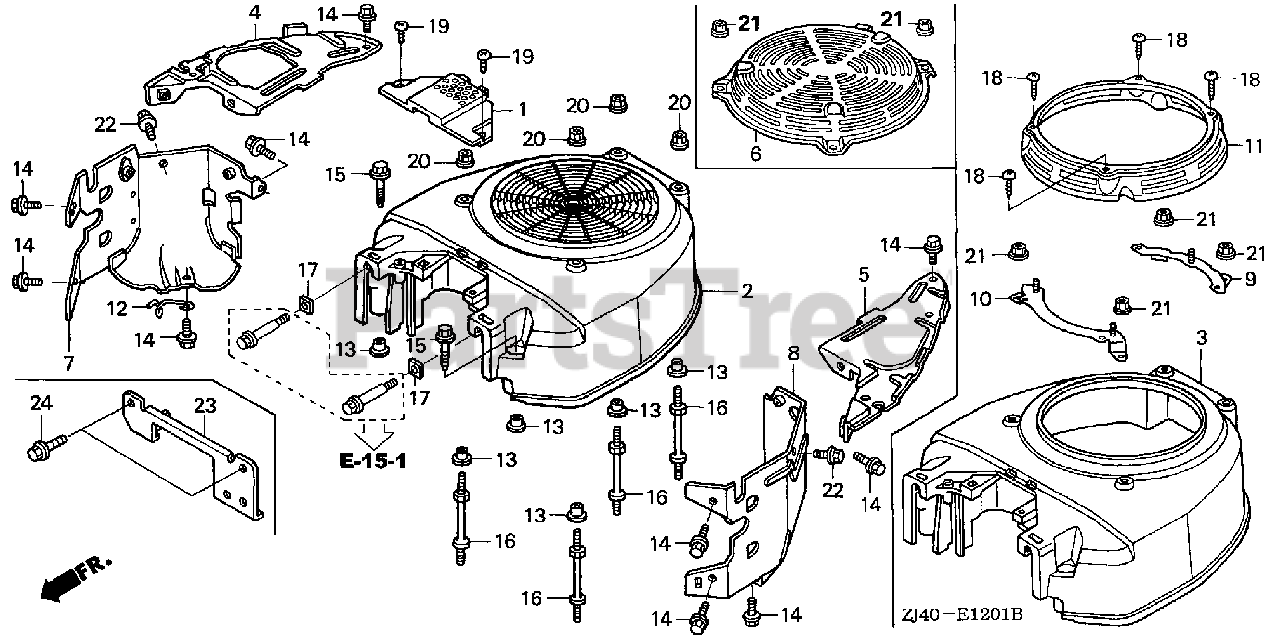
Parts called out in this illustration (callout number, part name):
1	COVER, FUEL PUMP
3	COVER, FAN *NH1* (RECOIL STARTER) (BLACK)
3	COVER, FAN *R280* (RECOIL STARTER) (POWER RED)
4	PLATE, SIDE
5	PLATE, SIDE
9	STAY A, RECOIL STARTER
10	STAY B, RECOIL STARTER
11	COVER, RECOIL STARTER STAY *NH1* (BLACK)
11	COVER, RECOIL STARTER STAY *R280* (POWER RED)
12	CLAMP, IGNITION TUBE
13	COLLAR B, TAILLIGHT
14	BOLT, FLANGE (6X12) (CT200)
15	BOLT, FLANGE (6X23) (CT200)
16	BOLT, STUD (6X71)
17	NUT, SQUARE (5MM)
18	SCREW, TAPPING (5X16)
19	SCREW, TAPPING (5X20)
21	NUT, FLANGE (6MM)
22	BOLT, FLANGE (6X8)
